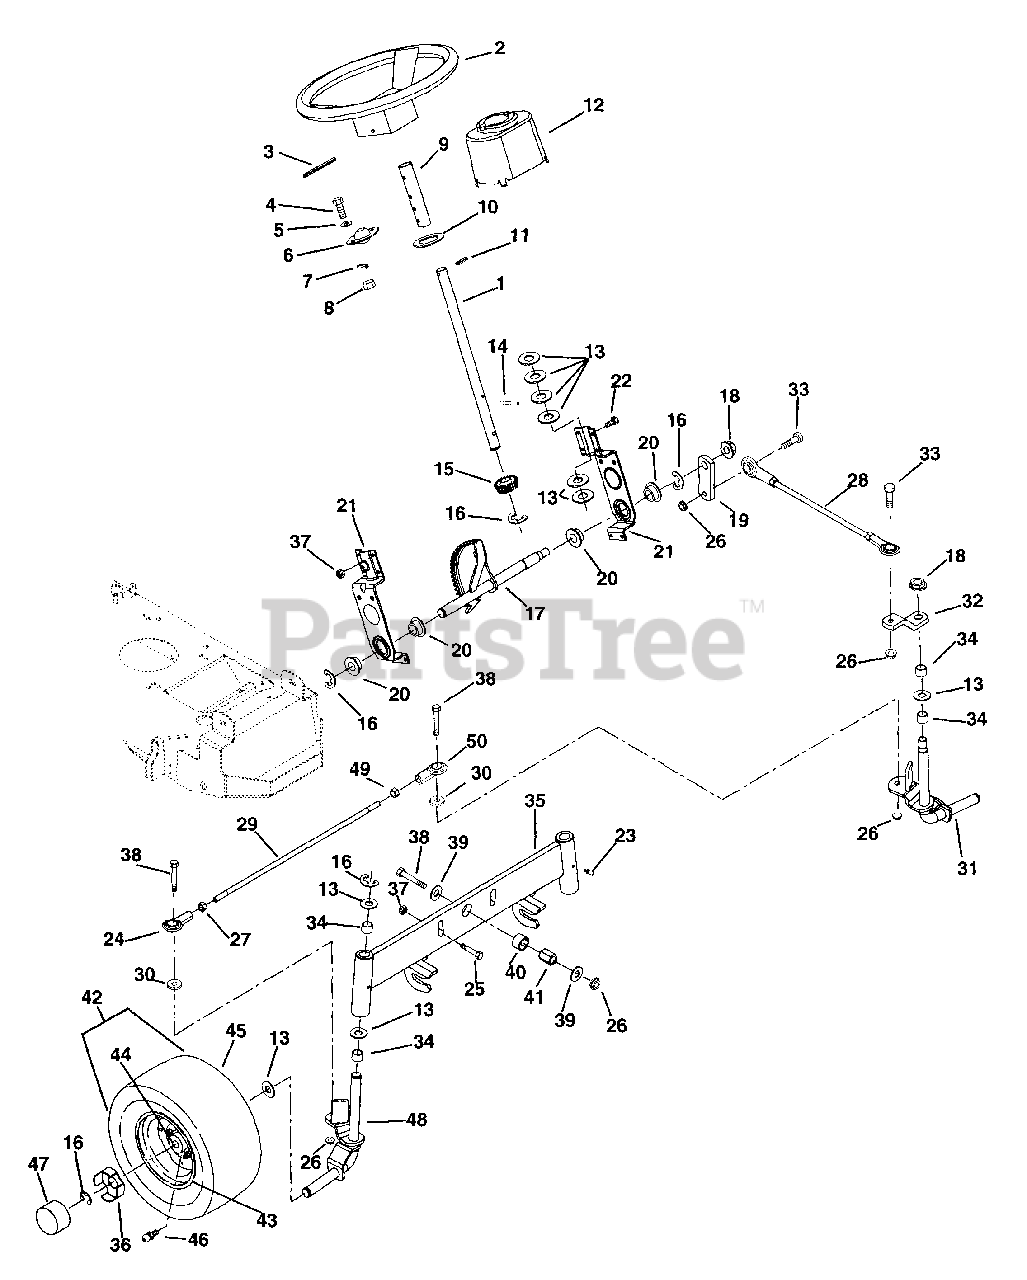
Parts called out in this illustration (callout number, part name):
1	Column Steering
2	Steering Wheel 13"
3	Pin-Roll .250 x 1.75
4	Bolt-Hex .31-18 x .75 Grade 5
5	Washer-Flat-Steel .312 x .734 x .065
6	Bearing-Flange .751 x 2 Holes x .81
7	Washer-Lock .312 x .097
8	Nut-Hex .31-18
10	Washer-Flat-Steel .754 x 1.125 x .062
11	Pin-Roll .250 x 1.00
12	Cone-Steering Column
13	Washer-Flat-Steel .755 x 1.375 x .062
14	Pin
15	Pinion Gear-Steering
16	Ring-Retaining-External .750 x .050
17	Gear-Steering
18	Nut-Locking .563-18 Grade 5
19	Arm-Steering Rod
20	Bushing-Flange .750 x 1.093 x .625 x 1.375
21	Bracket-Steering Gear
22	Bolt-Hex .250-20 x .75
23	Fitting-Lube .25-28 x .256
24	Rod End-.375-24
25	Bolt-Hex .38-16 x 1.25 Grade 5
26	Nut-Locking-Center .38-16
27	Nut-Jam .375-24
28	Link-Drag
30	Bushing-Sleeve .377 x .624 x .370
31	Spindle-Left Hand
32	Arm-Steering Spindle
33	Bolt-Button Head .38-16 x 1.25 Grade 5
34	Bushing-Sleeve .750 x .814 x 1.000
35	Axle-Front
36	Spindle Cup
37	Nut-Locking-Center .25-20
38	Bolt-Hex .38-16 x 1.75 Grade 5
39	Washer-Flat-Steel .38 x 1.500 x .125
40	Bushing-Sleeve .626 x 1.000 x .524
41	Bushing-Sleeve .377 x .623 x .775
42	Tire/Wheel Assembly 15 x 6.00-6
43	Rim
44	Bushing-3/4 Bore
45	Tire-Turf Saver 15 x 6.00-6 2 Ply
46	Fitting-Lube .25-28 x .97
47	Hub Cap
48	Spindle-Right Hand
49	Nut-Jam .375-24
50	Rod-End .375-24
